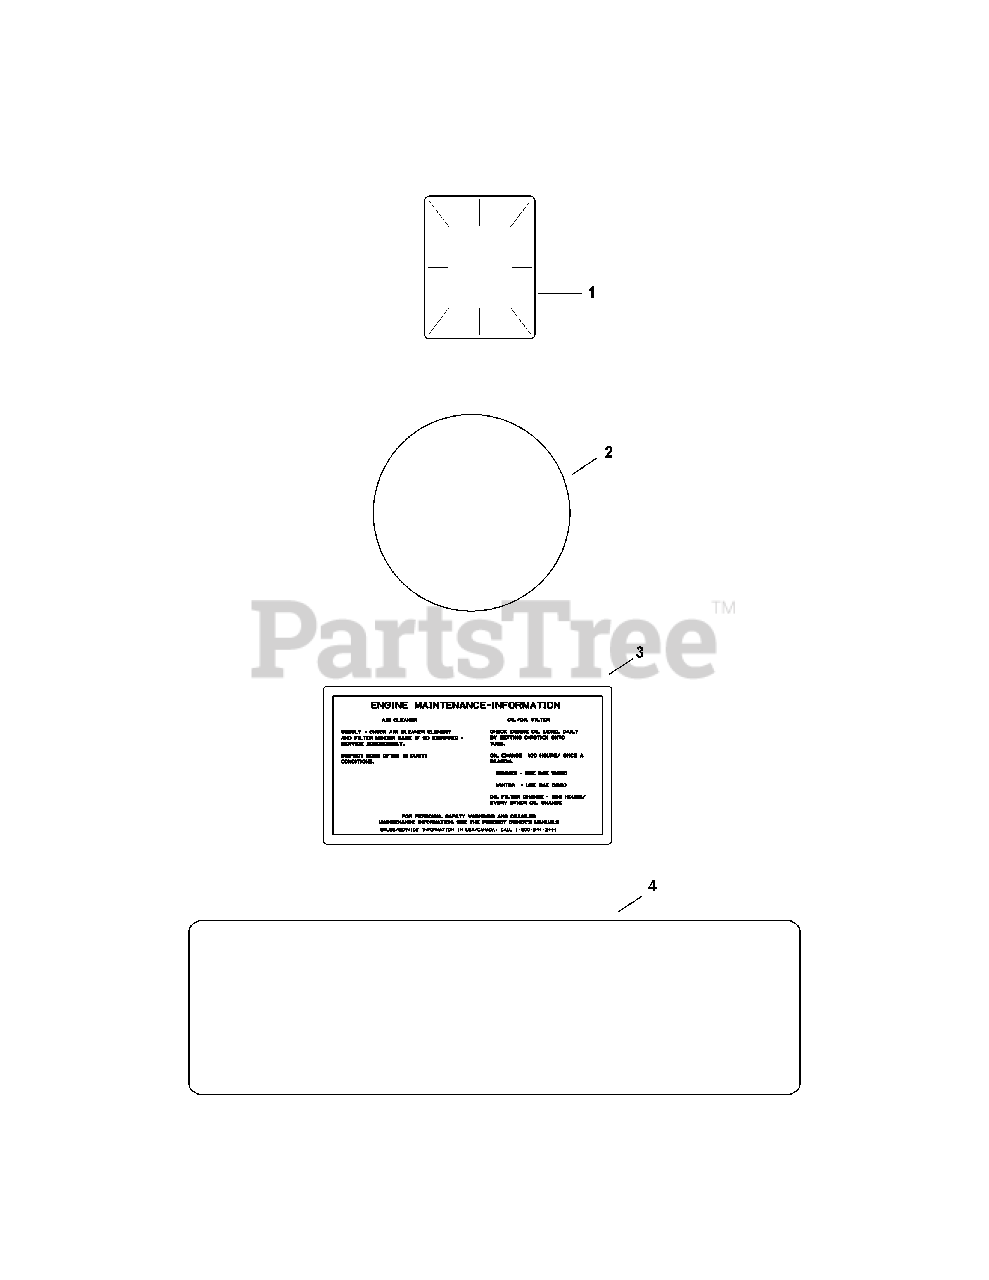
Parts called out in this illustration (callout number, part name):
1	DECAL, CLEAR LAMINATE
2	DECAL, GRASS SCREEN
3	DECAL, AIR CLEANER
